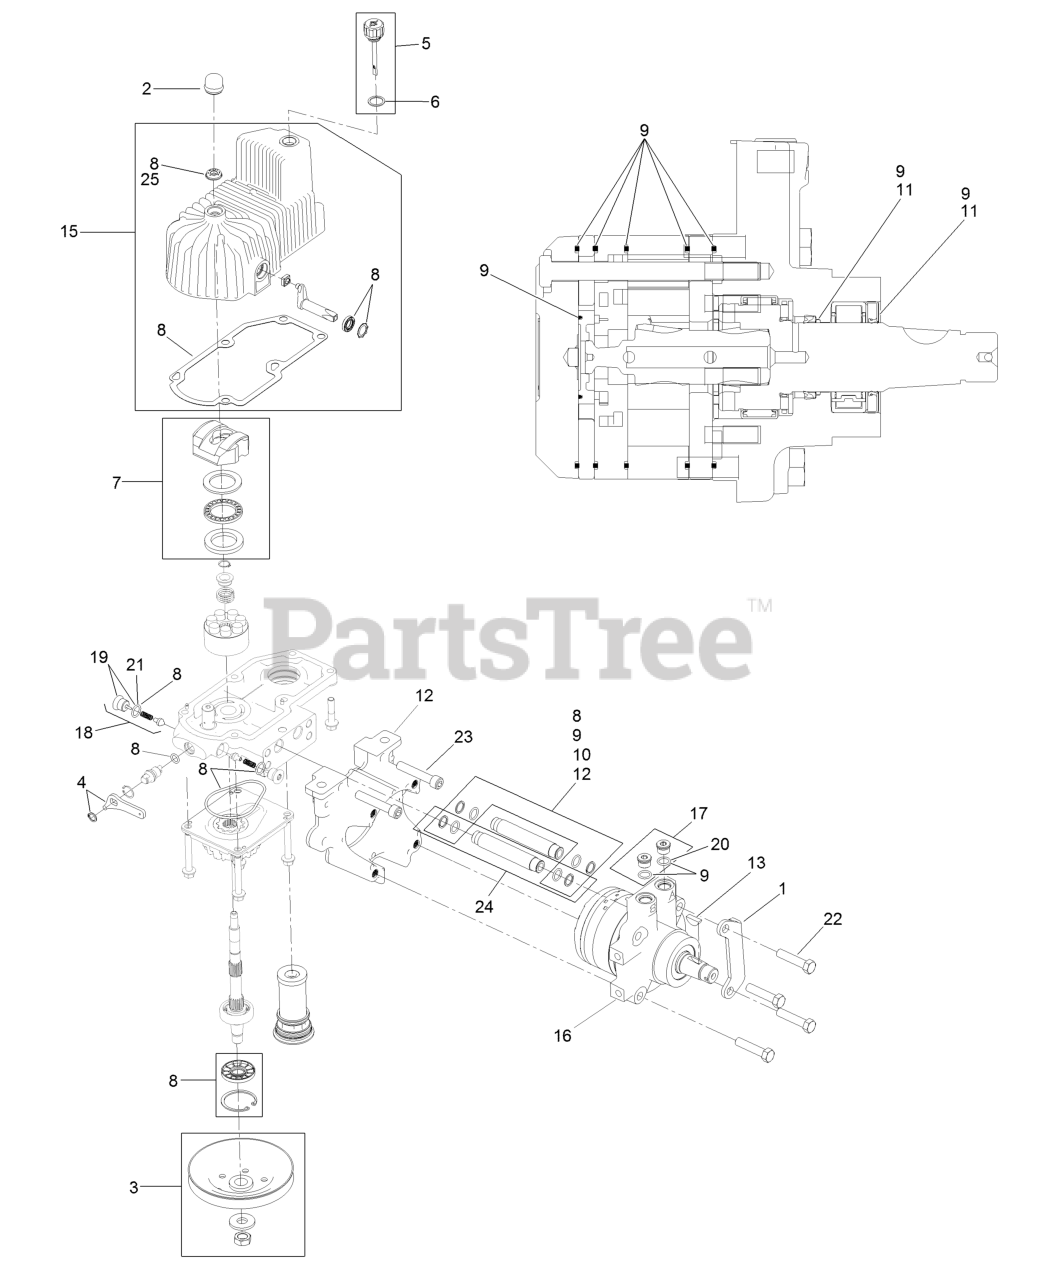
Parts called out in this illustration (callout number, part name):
1	Mount-Shoe, Horse
2	Cover-Shaft, Hydro
3	Pulley Kit
4	Handle-Bypass Valve,Hydro
5	Dipstick-Hydro W/Gasket
6	Gasket-Dipstick, Hydro
7	Swash Block Kit
8	Pump Seal Kit
9	Motor Seal Kit
10	Tube Seal Kit
11	Output Shaft Seal Kit
12	Nose Cup-Uht
13	Key-Woodruff
15	Housing-RH
16	Motor-Hydraulic RH 240Cc
17	Magnetic Plugs Service Kit
18	Check Valve ASM
19	Plug-Check (W/O-Ring)
21	O-Ring-Check Valve
22	Screw HH
23	Screw-HSH
24	Hydraulic Tube Kit
25	Seal-Fan Drive
99	Puller-Pulley
99	Flow Test Kit
